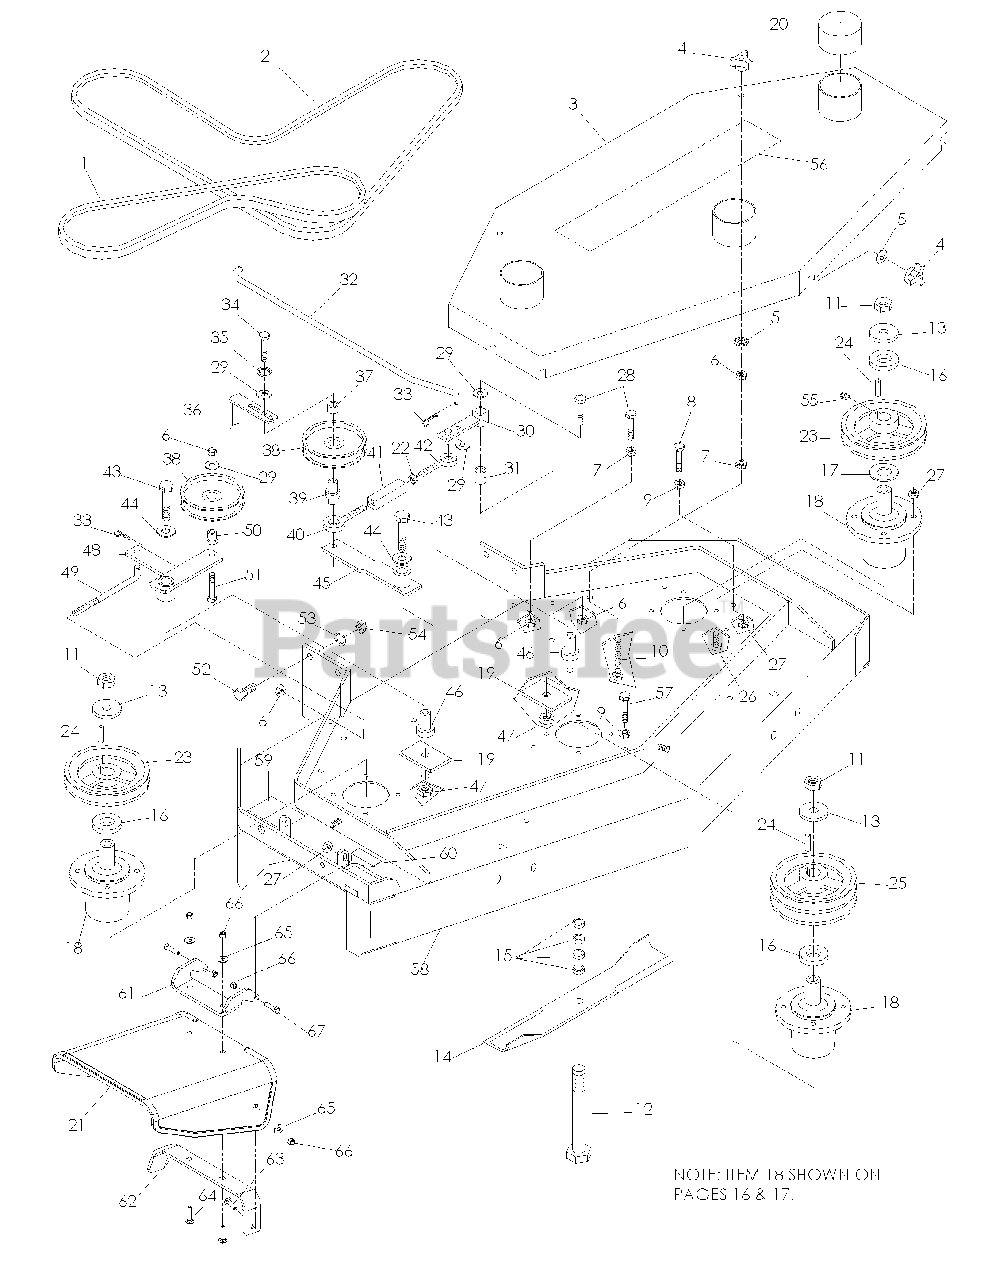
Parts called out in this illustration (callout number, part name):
1	BLADE BELT
2	BLADE BELT 48"
3	BELT SHIELD 48"
4	KNOB, THREE PRONG
5	WASHER 3/8 SEALING
6	HLN 3/8-16
7	HFLN 3/8 -16
8	HCS 5/16-18 x 3
9	HFLN 5/16-18
10	TAPBOLT, 3/8 -16 x 4 1/2
12	HCS 5/8-18 x 8 1/2
13	SUPPORT WASHER
14	BLADE 16 1/4"
15	BLADE SPACERS
17	BUSHING 10 GA.
18	HOUSING, CUTTER
21	DEFLECTOR CHUTE
22	NUT 1/16-18
23	PULLEY W/SETSCREWS
24	KEY 1/4 SQ x 1 1/8
25	DOUBLE PULLEY
26	HCS 5/16-18 x 1
27	HLN 5/16-18
28	HCS 3/8-16 x 2 1/4
29	WASHER 3/8
30	ENGAGEMENT ARM
31	SLEEVE BUSHING
32	BLADE ROD 48"
33	HAIRPIN #2
34	HCS 3/8 -16 x 2 1/2
35	LOCKWASHER 3/8
38	IDLER PULLEY
39	EYEBOLT PIVOT
40	EYEBOLT LH
41	TURNBUCKLE
42	EYEBOLT RH
43	HCS 1/2-13 x 2 3/4
44	WASHER 1/2
46	IDLER SPINDLE
47	NUT 1/2-13 NYLOC
48	AUX. IDLER ARM
49	TENSION ROD
50	IDLER FLANGE BUSHING
51	HCS 3/8 -16 x 1 3/4
52	HCS 7/16-14 x 1 1/2
53	LOCKWASHER 7/16
54	NUT 7/16-14
55	SETSCREW 5/16 NYLOC
56	DECAL, HUSQVARNA
57	HCS 5/16-18 x 4
58	48" DECK W/DECALS
59	DECAL, SEVERING
60	DECAL, CPSC
61	PIVOT BRACKET
62	BRACKET REINF
63	RHSNB 5/16-18 x 1 1/4
64	RHSNB 5/16-18 x 1 1/2
65	WASHER, 5/16
66	NUT 5/16-18 NYLOC
67	HCS 5/16-18 x 1 1/4
